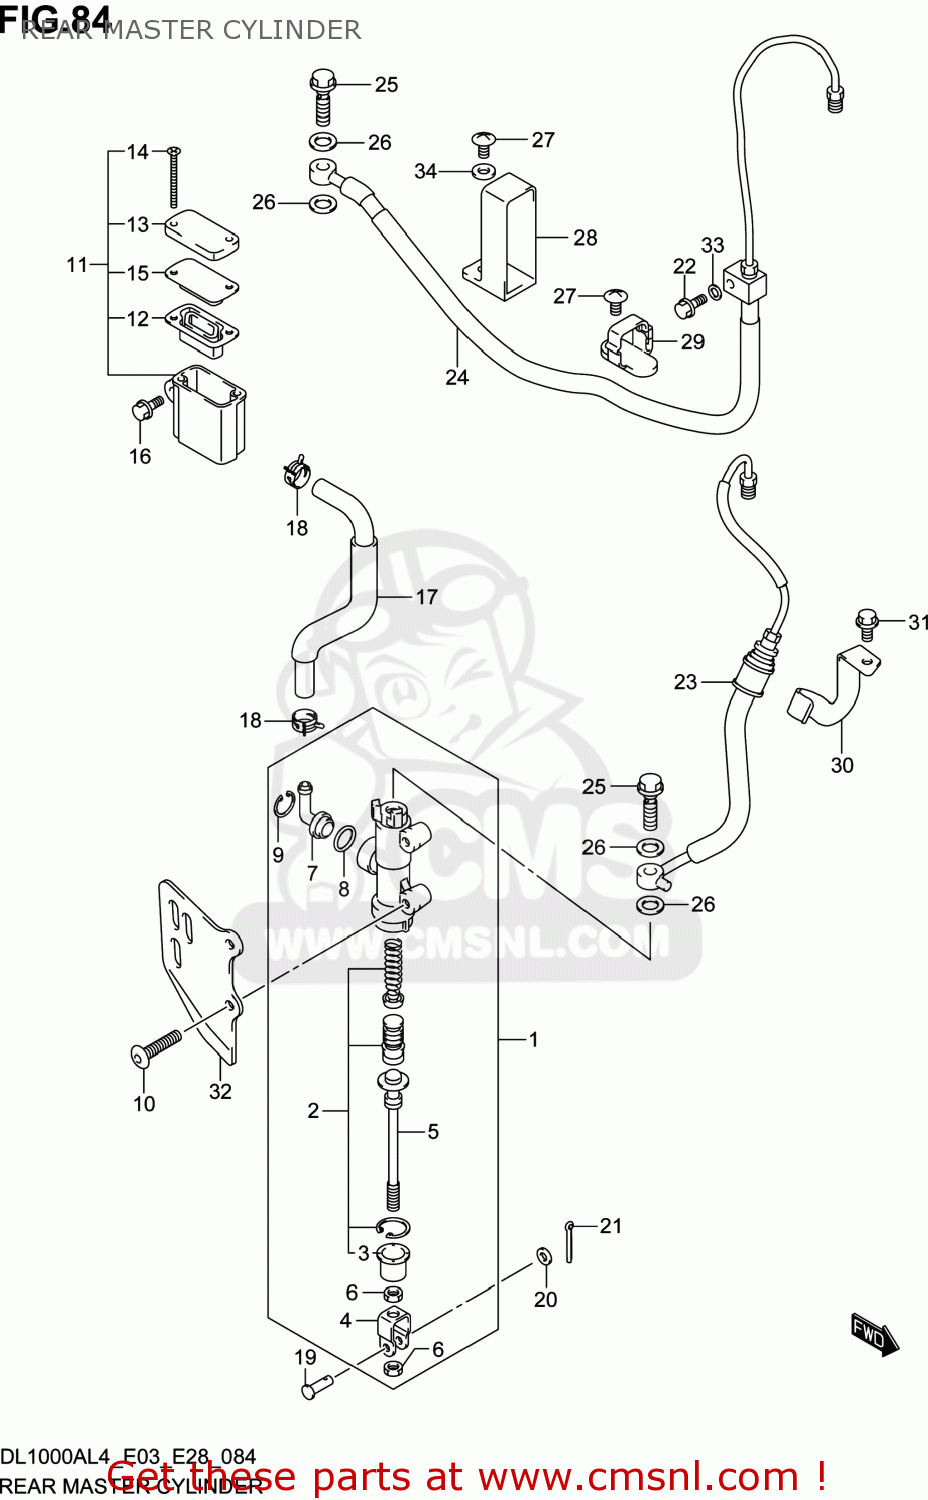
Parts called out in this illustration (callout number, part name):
1	CYLINDER ASSY,REAR MASTER
2	PISTON/CUP SET
3	BOOT
4	YOKE
5	ROD,PUSH
6	NUT
7	CONNECTOR
8	O RING
9	CIRCLIP
10	SCREW(6X25)
11	TANK ASSY,RESERVOIR
12	DIAPHRAGM
13	CAP
14	SCREW
15	PLATE,DIAPHRAGM
16	BOLT(6X16.5)
17	HOSE,RR RESERVOIR TANK
18	CLIP
19	PIN(6X18.2)
20	WASHER
21	PIN
22	BOLT
23	HOSE ASSY,RR MASTER TO UNIT
24	HOSE ASSY,RR UNIT TO CLPR
25	BOLT UNION
26	WASHER(10X15X1.5)
27	SCREW
28	GUIDE,RR BRAKE HOSE
29	GUIDE,RR BRAKE HOSE
30	CLAMP,RR BRAKE HOSE
31	BOLT
32	COVER,REAR MASTER CYLINDER
33	CUSHION,REAR BRAKE HOSE
34	WASHER
